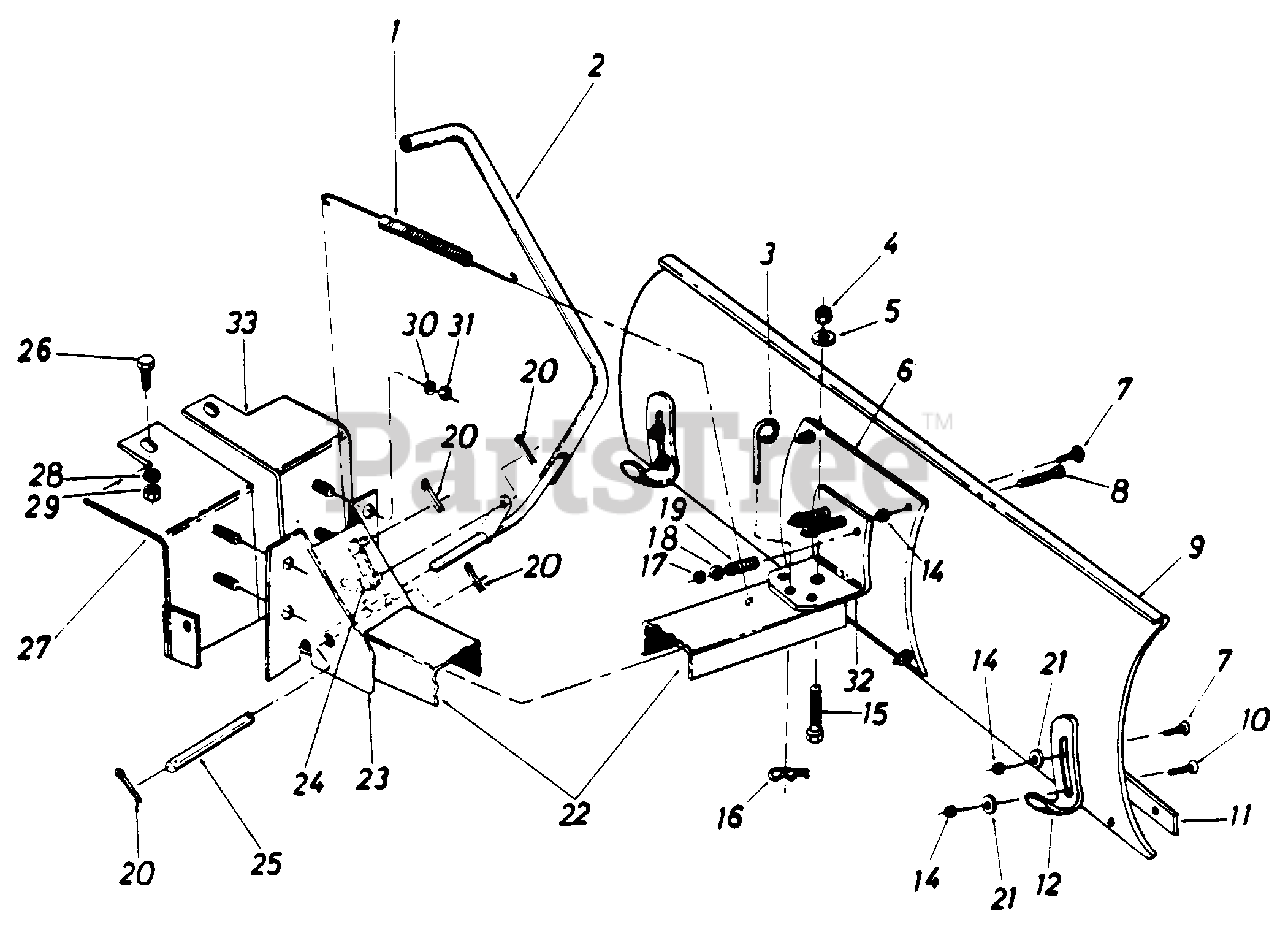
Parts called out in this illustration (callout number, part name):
1	Extension Spring
2	Lift Handle Ass'y.
3	Pivot Lock Pin
4	Hex Cont. L-Nut 1/2-13 Thd.
5	Fl-Wash. 17/32 I.D. x 1.25 Lg.
6	Reinforcement Plate
7	Carriage Bolt 5/16-18 x .75" Lg.
8	Hex Bolt 3/8-15 x 3.75 Lg. Grade 5
9	42" Blade
10	Carriage Bolt 5/16-18 x 1 Lg.
11	42" Weu Plata
12	Shoe Skid
14	Hex Cent. L-Nut 5/1618 Thd.
15	Hex Bolt 1/2-13 x 1.25 Lg.
16	Int. Cotter Pin
17	Hex Cent. L Nut 3/8-16 Thd.
18	Fl-Wash. 3/8" 1.0.
19	Compression Spring
20	Cotter Pin 1/8 Dia X 1" Lg.
21	Fl-Wash. 5 .D.
22	Push Bar Channel
23	Pivot Support Bracket
25	Channel Pivot Shaft
26	Hex Bolt 3/8-16 x 1" Lg. Grade 5
27	Support Bracket-R.H.
28	L-Wash. 318 I.D.
29	Hex Nut 3/8-1B 0 Thd.
30	L-Wash. 3/8" I.D.
31	Hex Jam Nut 3/8-16 Thd.
32	Support Bracket
33	Support Bracket-L.H.
